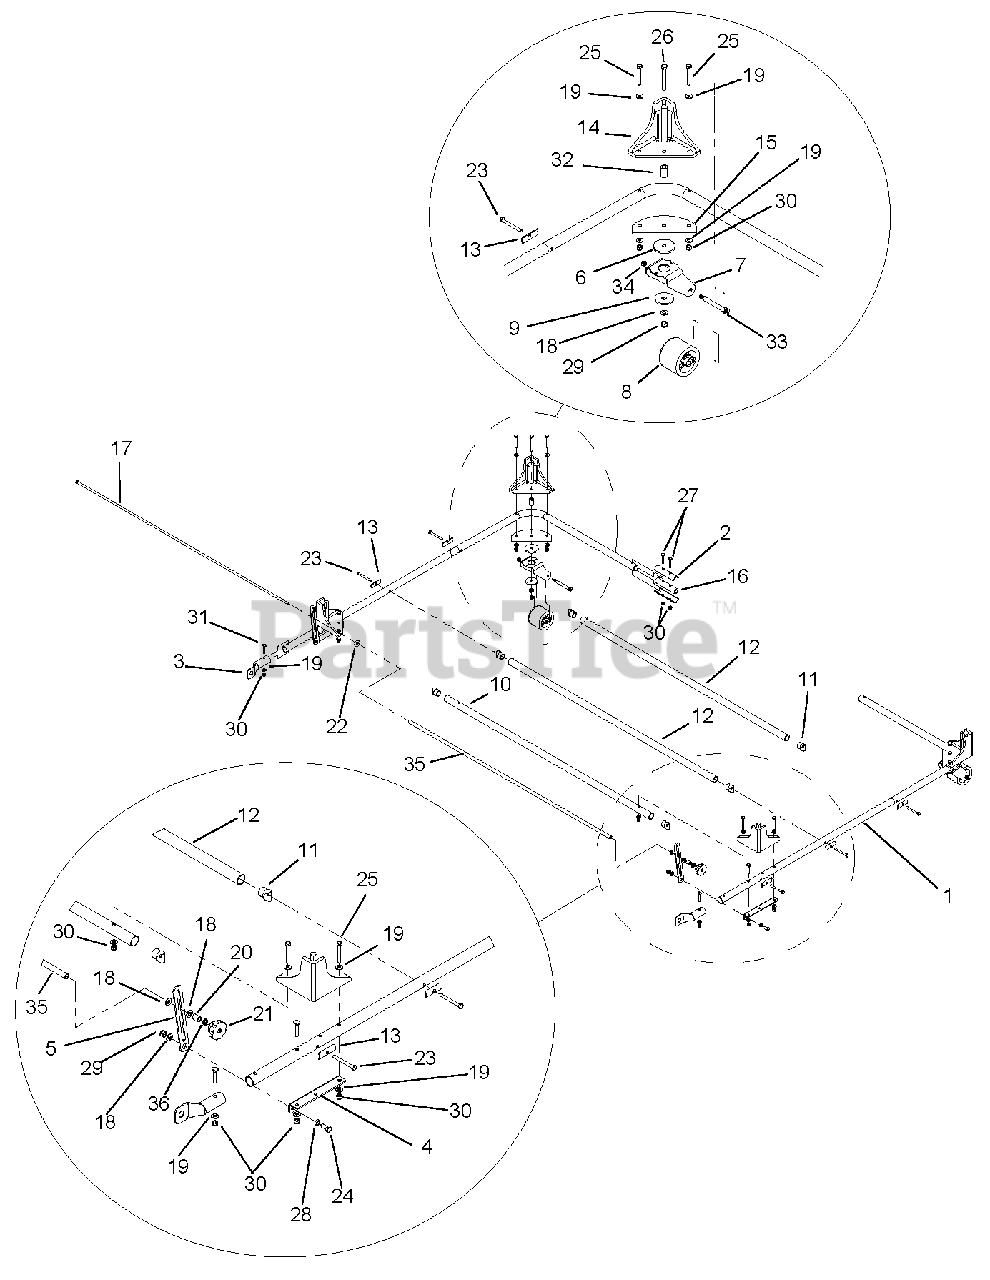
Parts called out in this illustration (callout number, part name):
12	2
18	5
19	20
22	1
24	1
25	8
26	2
27	2
29	3
30	14
34	2
